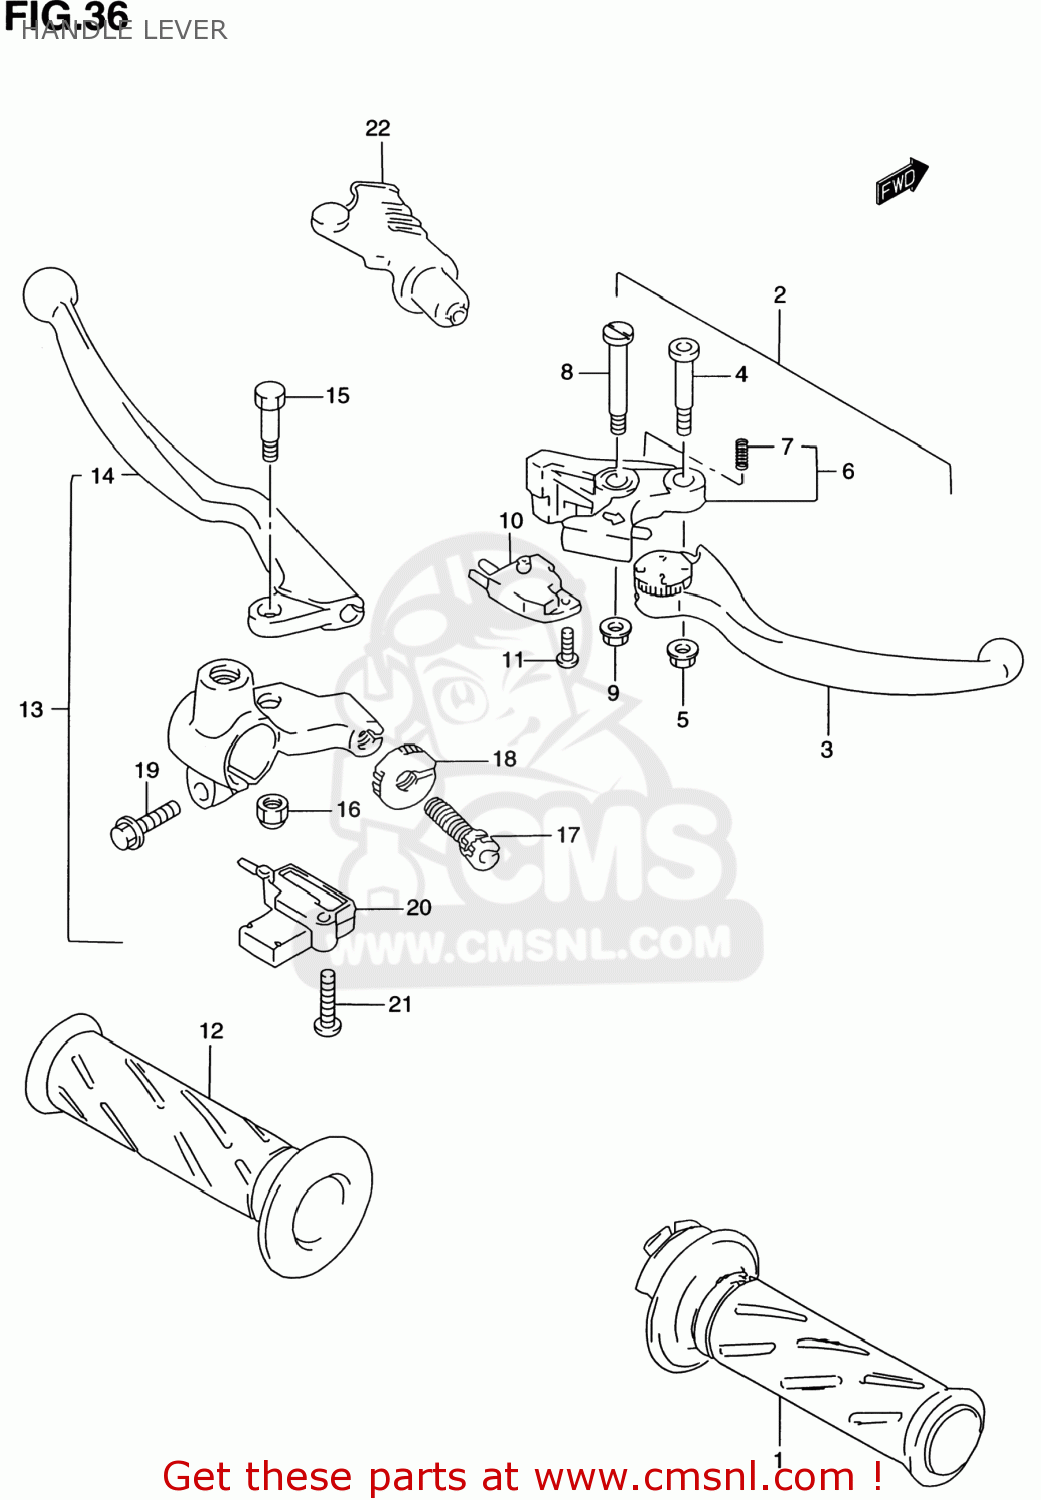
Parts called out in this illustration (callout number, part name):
1	GRIP,THROTTLE
2	LEVER ASSY,BRAKE
3	LEVER,ADJUST
4	BOLT,LEVER
5	NUT
6	KNOCKER
7	SPRING
8	BOLT,LEVER PIVOT
9	NUT
10	SWITCH ASSEMBLY,STOP
11	SCREW
12	GRIP,LEFT
13	LEVER ASSY,CLUTCH
14	LEVER,CLUTCH
15	BOLT,LEVER SET
16	NUT
17	ADJUSTER,WIRE
18	NUT,LOCK
19	SCREW
20	SWITCH,CLUTCH
21	SCREW
22	COVER,CLUTCH LEVER
